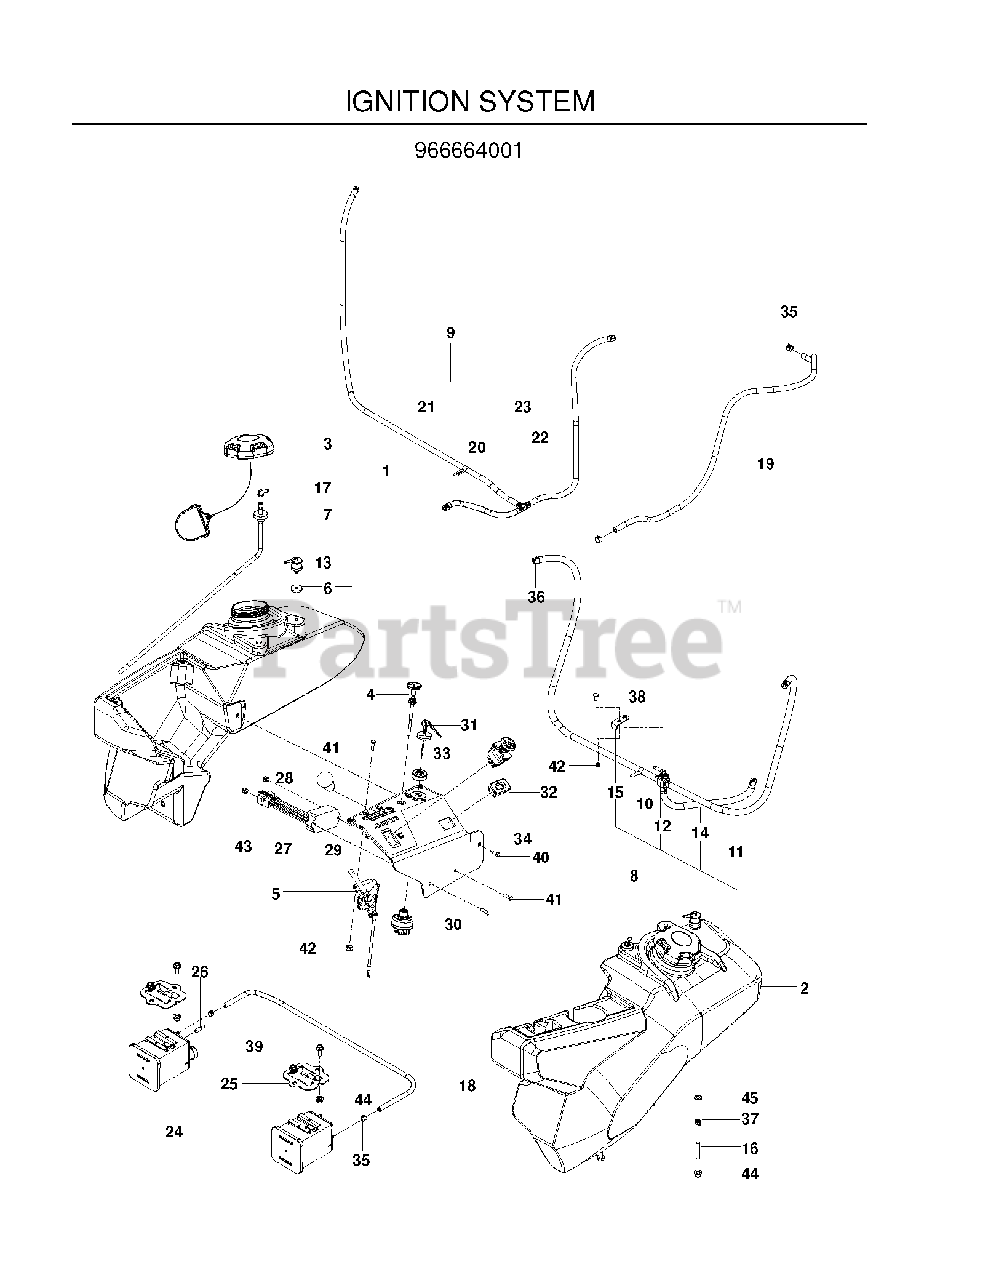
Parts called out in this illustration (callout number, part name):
3	CAP, FUEL
6	RUBBER GROMMET
7	GROMMET, CHECK VALVE
11	FUEL LINE 24"
12	FUEL VALVE
13	VALVE, FUEL CHECK
14	FUEL LINE (5")
16	STUD, 5/16C
18	HOSE, VAPOR 3/16 X 30"
21	HOSE, VAPOR 3/16 X 39"
22	HOSE, FUEL, 3/16" X 20"
24	CANNISTER, CARBON
25	BRACKET, CANISTER
27	TIMER, SEAT
28	KNOB - SHIFT
30	SWITCH, IGNITION, INDAK
31	KEY, IGNITION
32	HOUR METER
33	SWITCH, PTO 10 AMP
35	CLAMP, HOSE
36	HOSE CLAMP
38	RHSNB 3/8C X 1
39	HHFS 5/16-18 X 3/4
40	SCR #10-24 X 3/8 SKT HD BLK OX
41	SCR #10-24 X .75 SKT HD BLK
42	NUT 3/8-16 HEX FLG NYLOC ZD
43	NUT 10-24 NYLOC
44	5/16-18 NYLOC FLANGE NUT
45	FLAT WASHER 5/16 SAE
